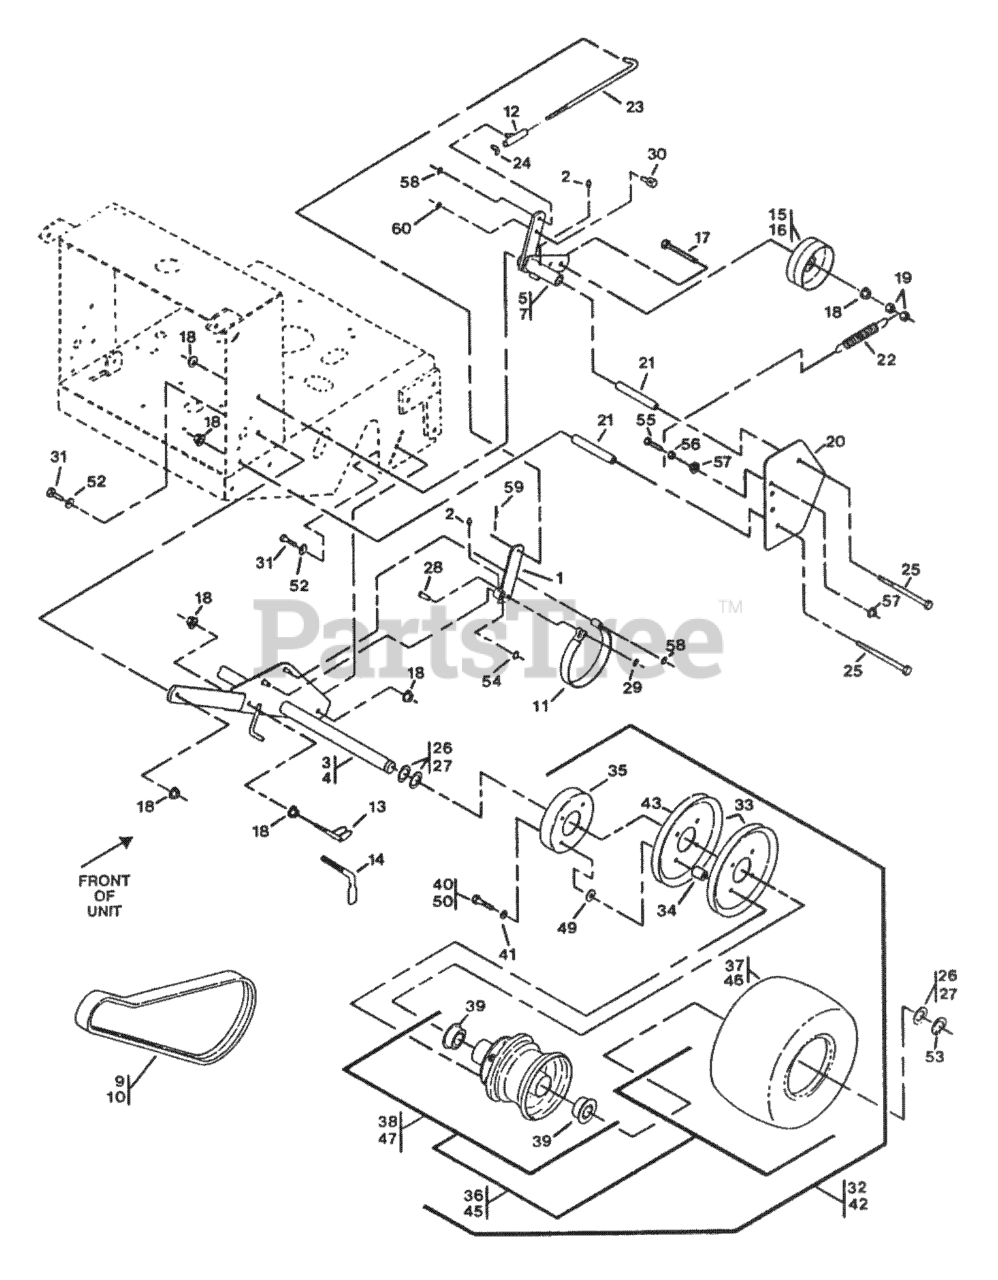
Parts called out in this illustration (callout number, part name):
9	BELT,WHEEL DRIVE
10	BELT-WHEEL, DRIVE
11	BAND-BRAKE
14	SCRAPER
15	IDLER-WHEEL, DRIVE
16	IDLER-WHEEL, DRIVE
20	SHIELD-WHEEL, DRIVE
21	SPACER-SHIELD
22	SPRING-EXTENSION
23	ROD-BRAKE
24	WINGNUT-NYLOCK
26	WASHER-SPACER
27	WASHER-SPACER
28	PIN-CLEVIS
29	RING-RETAIN,PUSH,EXT,FLAT
30	SWIVEL-SHORT, ADJUSTABLE
33	SHEAVE-WHEEL, DRIVE
34	SPACER-SHEAVE, WHEEL
35	DRUM-BRAKE
38	WHEEL AND HUB ASM
39	BEARING-FLANGED
41	WASHER-LOCK
42	DRIVE WHEEL ASM
43	SHEAVE-WHEEL, DRIVE
45	WHEEL AND TIRE ASM
47	WHEEL AND HUB ASM
53	RING-SNAP
59	PIN-COTTER
